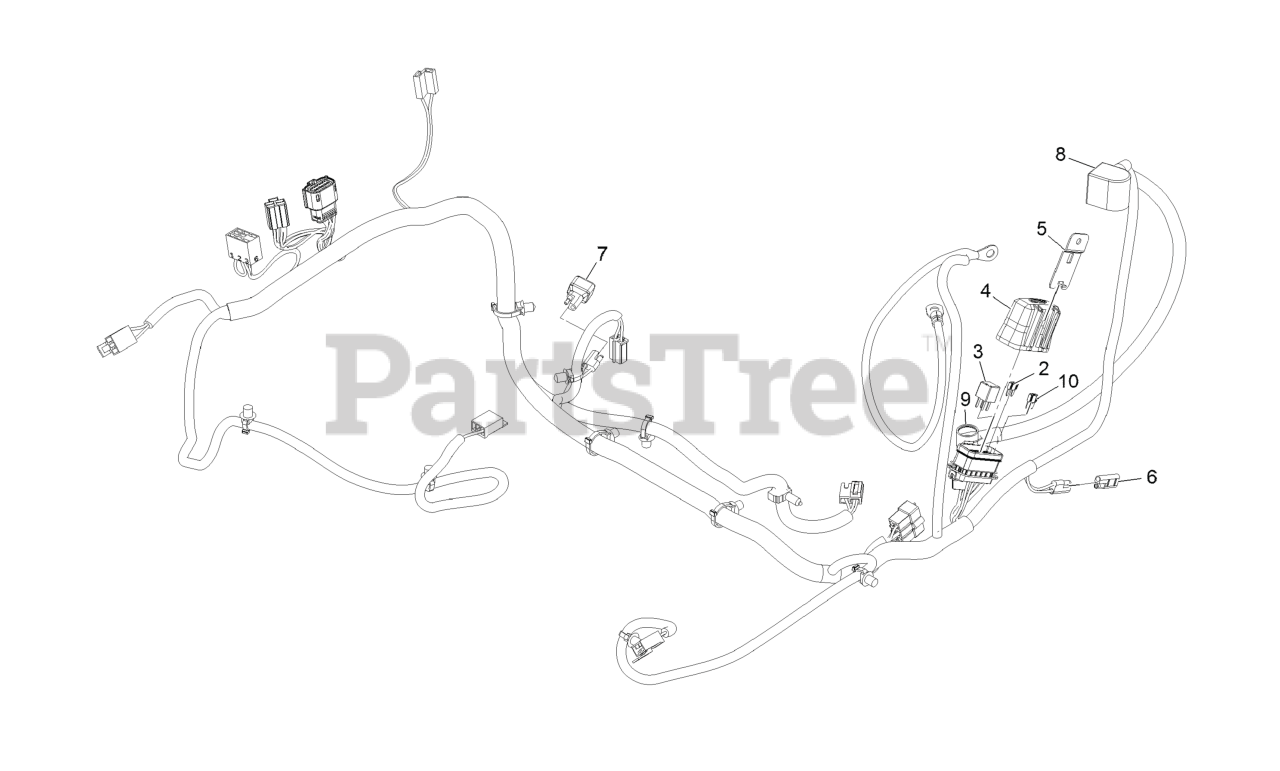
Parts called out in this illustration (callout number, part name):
2	FUSE-MINI BLADE, 20 AMP
3	RELAY-MICRO
4	COVER-BLOCK, FUSE
5	CLIP-MOUNTING
6	CAP-PLUG
8	INSULATOR-BATTERY
9	INSULATOR-SOLENOID
10	FUSE-MINI BLADE, 15 AMP
